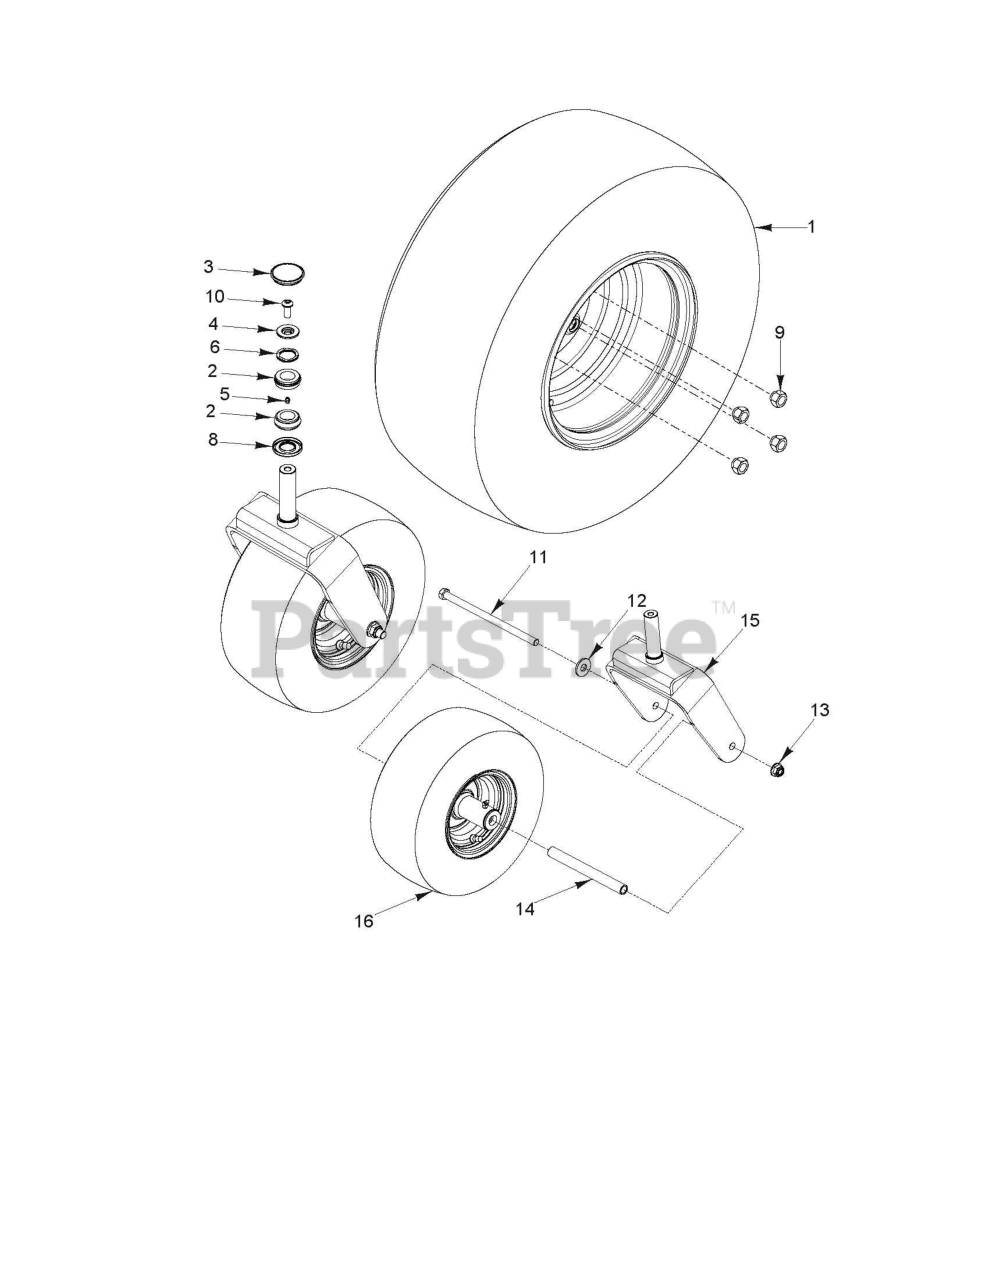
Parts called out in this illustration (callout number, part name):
1	Wheels
2	TAPERED ROLLER BRG
3	Caps
4	CAP SPRING. MZ/MZT CASTER RAW
5	Zerks
6	SPRING NESTED WAVE MZ/MZT
8	SEAL
9	Nuts
10	SCREW HEXALOBULAR SOCKET BUTTO
11	GSPW Screws
12	Washers
13	NUT 1/2-13 HEX FLANGE NYLOK CL
14	SPACER, PIVOT
15	Forks
16	ASM.TIRE.BLACK.MS.428
